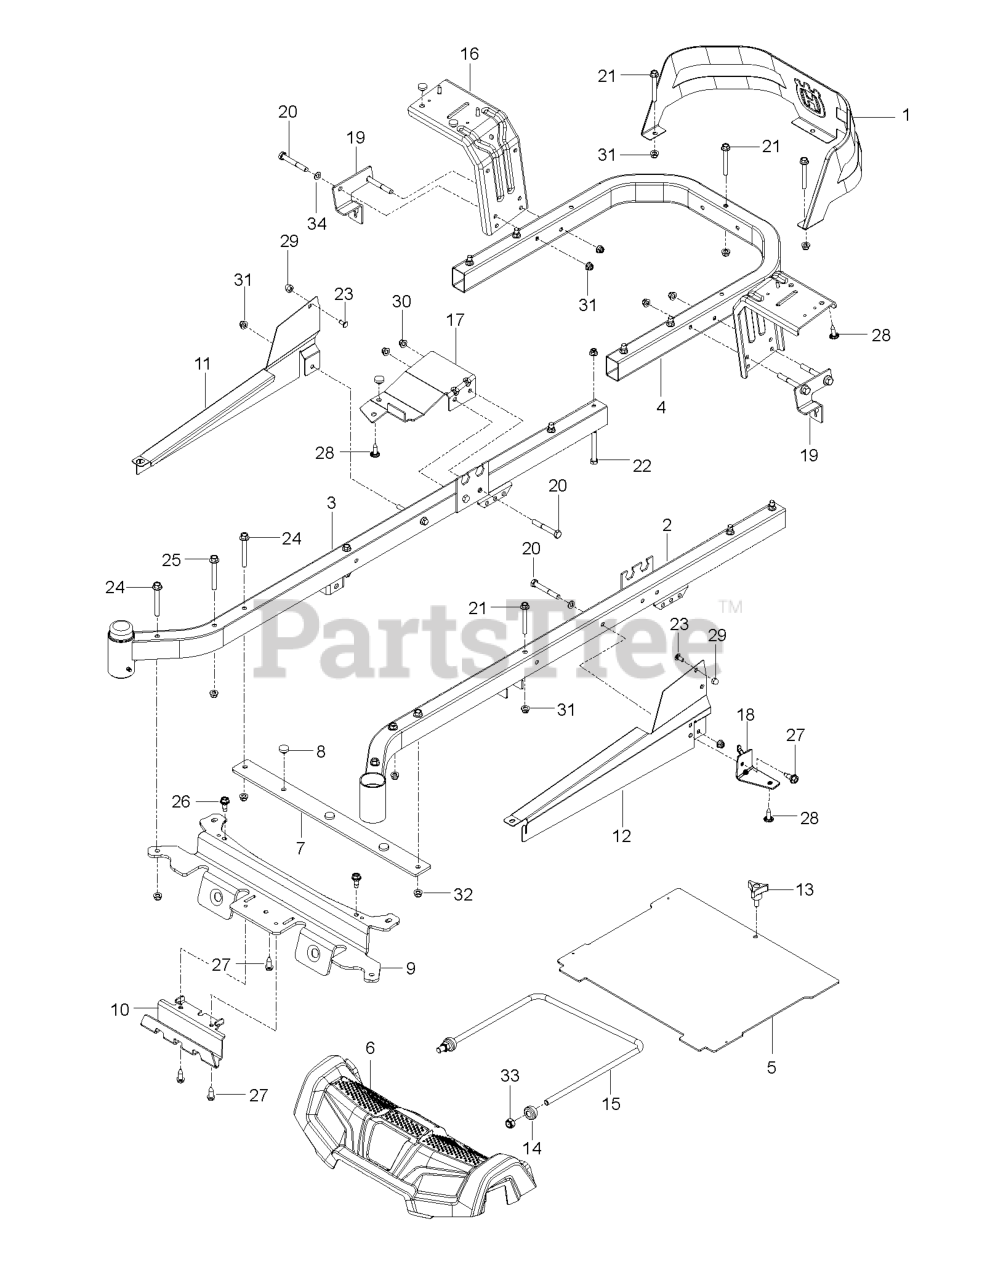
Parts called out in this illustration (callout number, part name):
1	GUARD.ENGINE.HUSQ.RZ.X498
2	Tube Frame, Rz.Main.We
3	FRAME TUBE LH.
4	TUBE.PNT.FRAME.RER.HUSQ.23".RZ
5	PLATE, FOOT W/DECALS RZ
6	COVER.FOOTREST.REFRESH.ASM
7	FOOTREST.PLATE.SUPPORT.X431
8	GROMMET.BUMPER
9	CROSS.PNT.MEMBER.BLK
10	SKID.PLATE.PNT.RZ.REF.SIVER
11	COVER.RAIL.RH.RZ.X668
12	COVER.RAIL.LH.RZ.X668
13	KNOB W/STUD
14	BUSHING SPHERICAL SUSP. FRONT
15	LINK, FRONT SUSP.
16	FENDER.SUPPORT.PNT.X431
17	SUPPORT.PNT.RH.CONSOLE.FRONT
18	SUPPORT.PNT.LH.CONSOLE.FRONT
19	BRKT ROD.BYPASS.EZT.X431
20	BOLT.FIN HEX 5/16-18UNC X2 1/4
22	BOLT.HEX.FIN.3/8-16 X 3.GR5
23	BOLT.CARRIAGE.5/16-18.7/16
24	HHFS 3/8-16 X 3 GRD 5 ZD
25	BOLT SHOULDER,FLANGED,3/8-16X3
26	BOLT.5/16-18.THRD.ROLL.SHOULDR
27	BOLT.5/16HEX.WHS.HD
28	SCREW.#10 X 0.750.BOS
29	NUT ACORN,FLANGED,5/16-18
30	NUT LOCK HEX FLANGE 5/16-18
31	5/16-18 NYLOC FLANGE NUT
32	NUT 3/8-16 HEX FLG NYLOC ZD
33	7/16-14 HEX NUT W/NYL RING ZD
34	WASHER - 15X7.3X1.6
